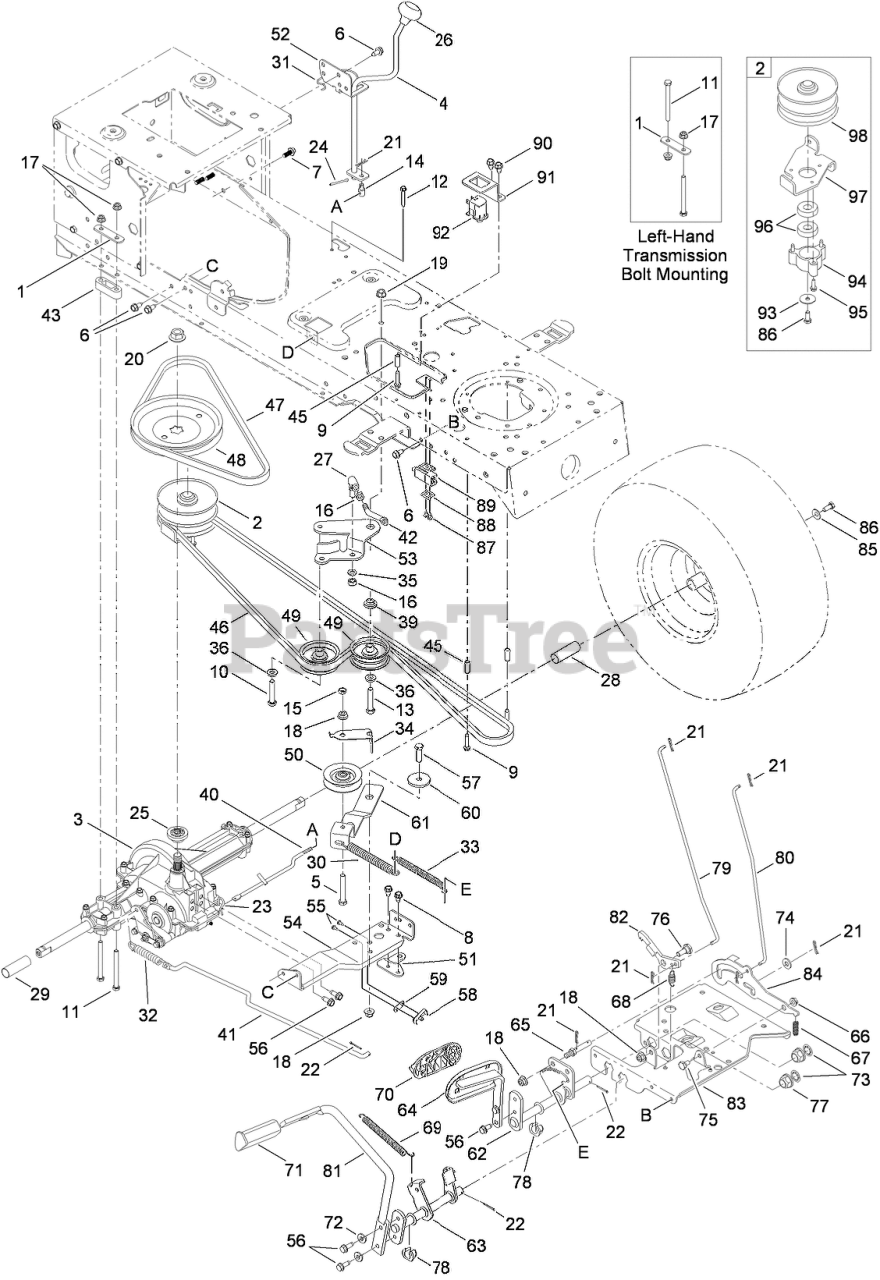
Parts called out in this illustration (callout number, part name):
1	BRACKET-MOUNTING, TRANSMISSION
2	PULLEY ASM
3	SINGLE SPEED TRANSAXLE ASM
4	SHIFT LEVER ASM
5	SCREW-HH
6	SCREW-TAP
7	SCREW-HH
8	SCREW-TAP
9	SCREW-HH
10	SCREW-TAP
11	SCREW-HH
12	SCREW-HH
13	SCREW-HH
14	FERRULE-ADJUSTABLE
15	NUT-JAM, LOCK
16	NUT-HEX
17	NUT-LOCK, FLANGE
18	NUT-LOCK, FLANGE
19	NUT-LOCK, FLANGE
20	NUT-FLANGE
21	PIN-COTTER
22	PIN-COTTER
23	PIN-HAIR
24	PIN-COTTER
25	HUB-PULLEY, SPLINE
26	KNOB-SHIFT
27	SCREW-HH
28	SLEEVE
29	SLEEVE
30	SPRING-EXTENSION
31	CLIP-SPRING, SHIFTER
32	SPRING-EXTENSION
33	SPRING-EXTENSION
34	KEEPER-BELT
35	WASHER-LOCK
36	WASHER-FLAT
39	SPACER-SHOULDER
40	ROD-SHIFT
41	ROD-BRAKE
42	ROD-ADJUSTMENT, IDLER
43	SPACER-TRANSAXLE
45	SPACER
46	BELT-DRIVE, VARIABLE SPEED
47	BELT-DRIVE, TRANSMISSION
48	PULLEY-V (W/HUB)
49	PULLEY-IDLER, FLAT
50	PULLEY-IDLER, V-TYPE
51	BRACKET-SHIFT
52	BRACKET-SHIFT
53	BRACKET-IDLER, CENTER DOUBLE
54	BRACKET ASM
55	SCREW-HWHTF
56	SCREW-HWH
57	SCREW-HH
58	SWITCH-SPRING, SHORT
59	PLATE-INSULATOR
60	SPACER-SHOULDER
61	BRACKET-IDLER
62	SPEED CONTROL ASM
63	SPEED CONTROL ASM
64	PEDAL ASM
66	NUT-LOCK, FLANGE
67	SPRING
68	SPRING-EXTENSION
69	SPRING-EXTENSION
70	PAD-PEDAL
71	PAD-BRAKE
72	WASHER-LOCK
73	WASHER-FLAT
74	Washer-Flat
75	BOLT-SHOULDER
76	BOLT-SHOULDER
77	BEARING-FLANGE
78	BEARING-FLANGE, HEX (SPLIT)
79	ROD-BRAKE, LOCK
80	ROD-CONTROL, CRUISE
81	PEDAL-BRAKE
82	LATCH-CRUISE
83	BRACKET-SUPPORT, STEERING
84	BRACKET-LOCKOUT
85	WASHER-BELL
86	SCREW-HH
87	SCREW-TAP
88	PLATE-SWITCH
89	SWITCH-INTERLOCK
90	SCREW-HWHTF
91	BRACKET-SWITCH, PARKING BRAKE
92	SWITCH-MOUNT, SNAP
93	WASHER-FLAT
94	CUP-BEARING
95	SCREW-HWH
96	BEARING-BALL
97	BRACKET-PULLEY
98	PULLEY ASM
